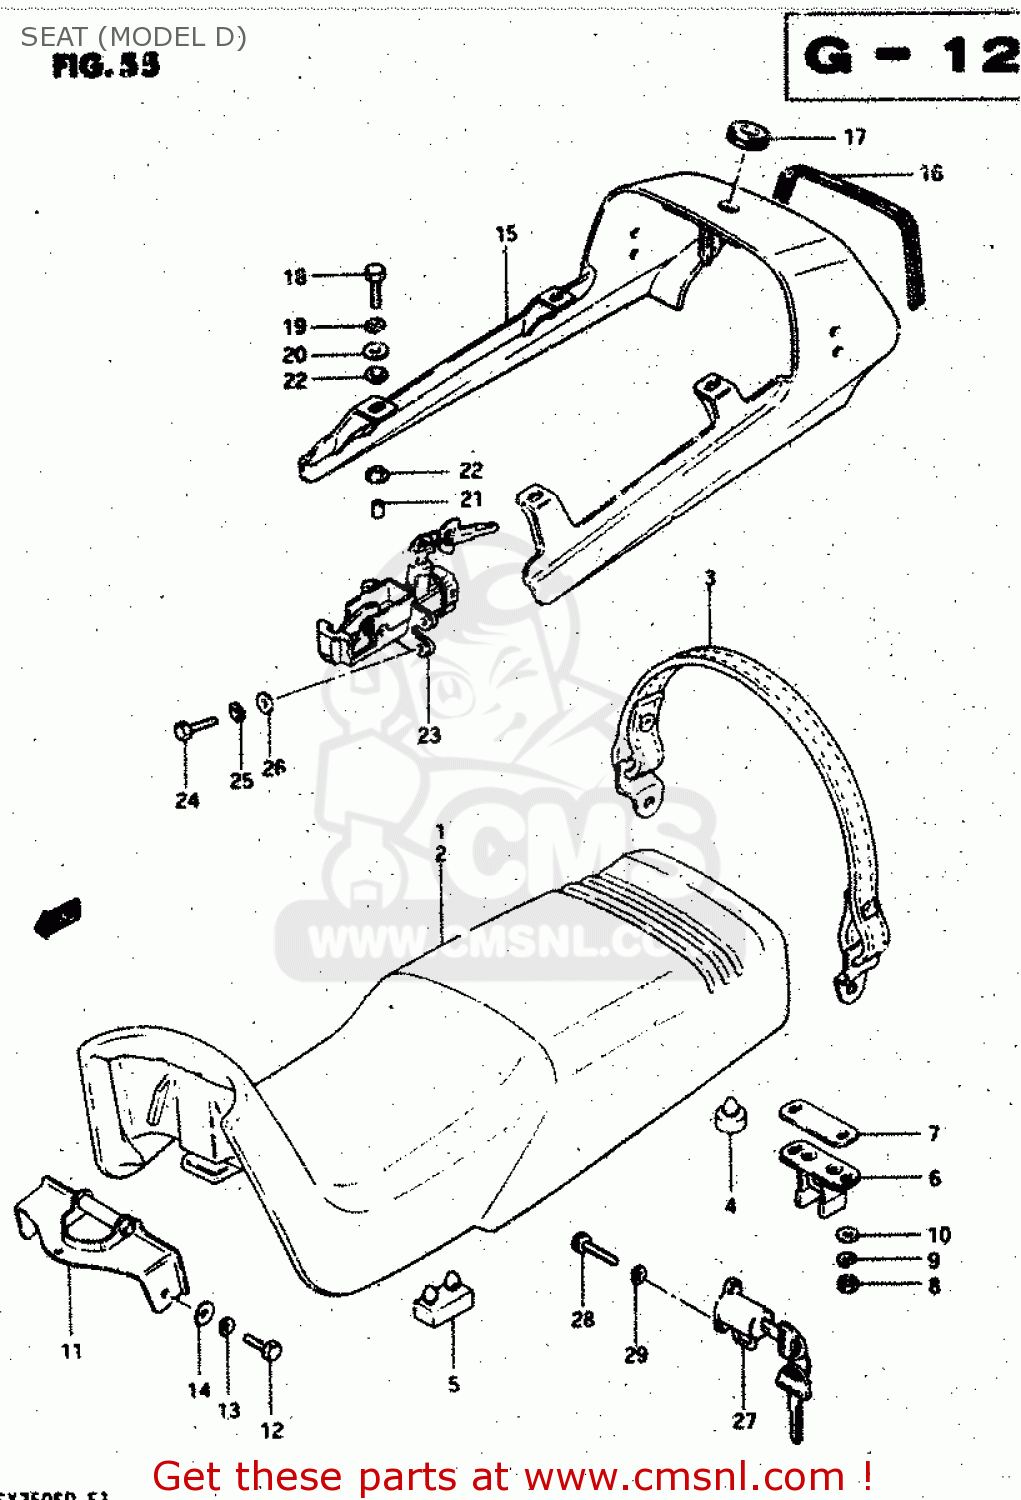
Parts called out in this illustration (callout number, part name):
1	SEAT ASSY
2	SEAT ASSY
3	BAND, SEAT GRIP (GRAY)
4	CUSHION
5	CUSHION
6	STRIKER,SEAT LOCK
7	SHIM,SEAT LOCK STRIKER
8	NUT 6MM
9	LOCK WASHER
10	WASHER
11	PLATE,SEAT HOOK FR
12	BOLT
13	LOCK WASHER
14	WASHER
15	COVER,SEAT TAIL
16	MOLE,SEAT TAIL COVER
17	GROMMET,SEAT LOCK HOLE
18	BOLT
19	LOCK WASHER
20	WASHER (6.5X24X1.6)
21	SPACER (7X10X12)
22	CUSHION
23	LOCK SET
24	BOLT
25	LOCK WASHER
26	WASHER
27	LOCK ASSEMBLY,HELMET
28	BOLT
29	LOCK WASHER
